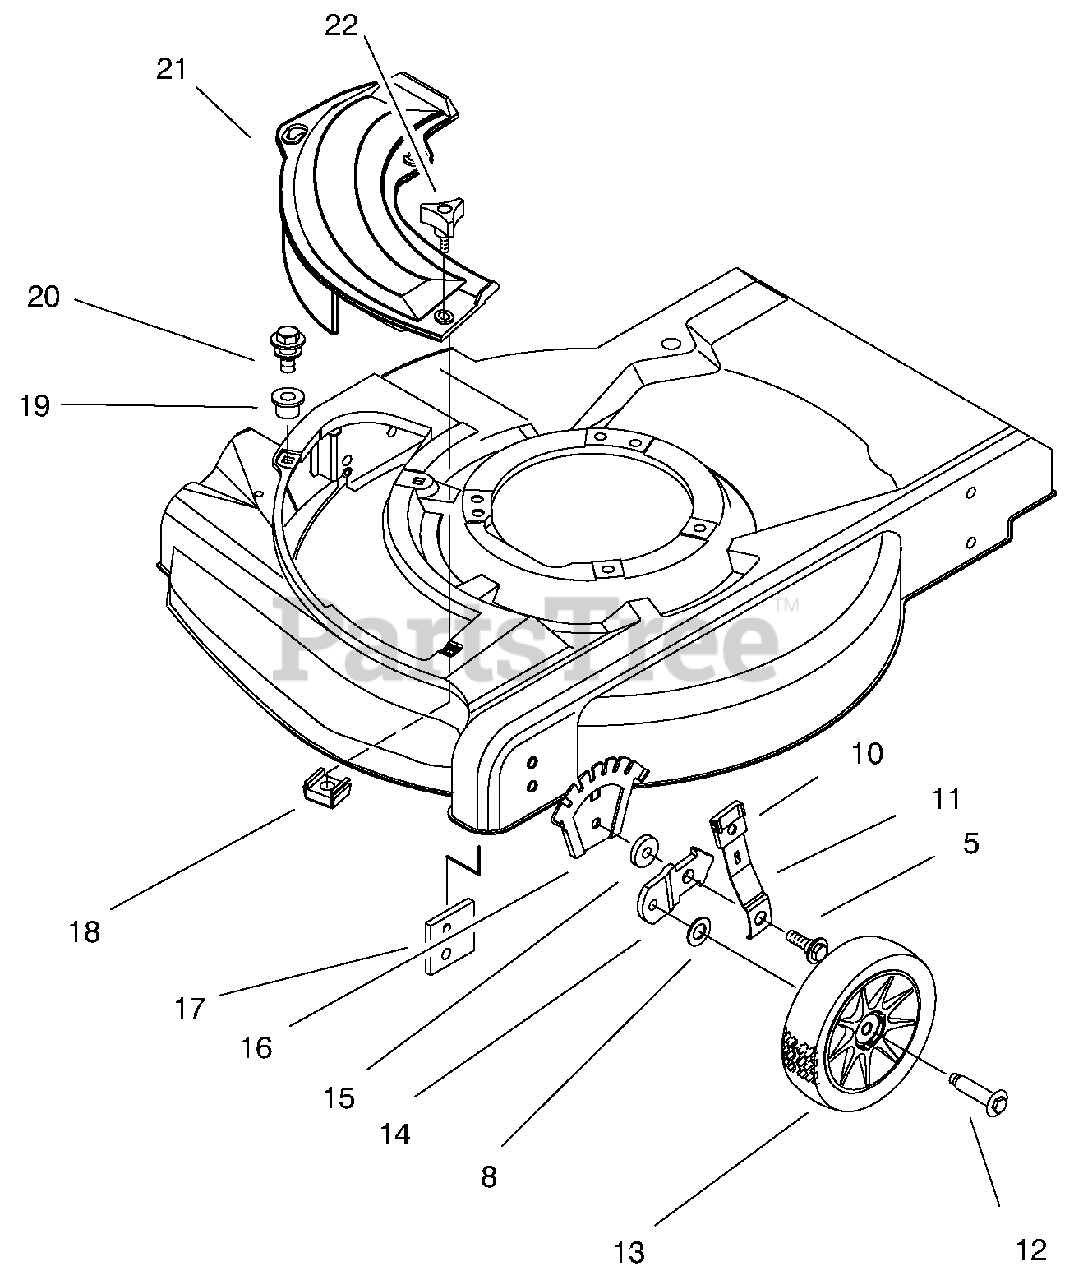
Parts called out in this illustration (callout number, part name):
5	Bolt-Shoulder Height Adj.
10	Knob-Height Adjust
11	Arm-Spring
12	Bolt-Shoulder
13	Wheel & Tire Ass'y 6"
14	Bracket-Wheel Height Adj.
16	Plate-Height Adj.
17	Plate-Baffle
18	Nut-Cage
19	Grommet-Plastic
20	Screw-Sems Thr'd Form.
21	Plate-Mulch
22	Knob-Cover Plate
